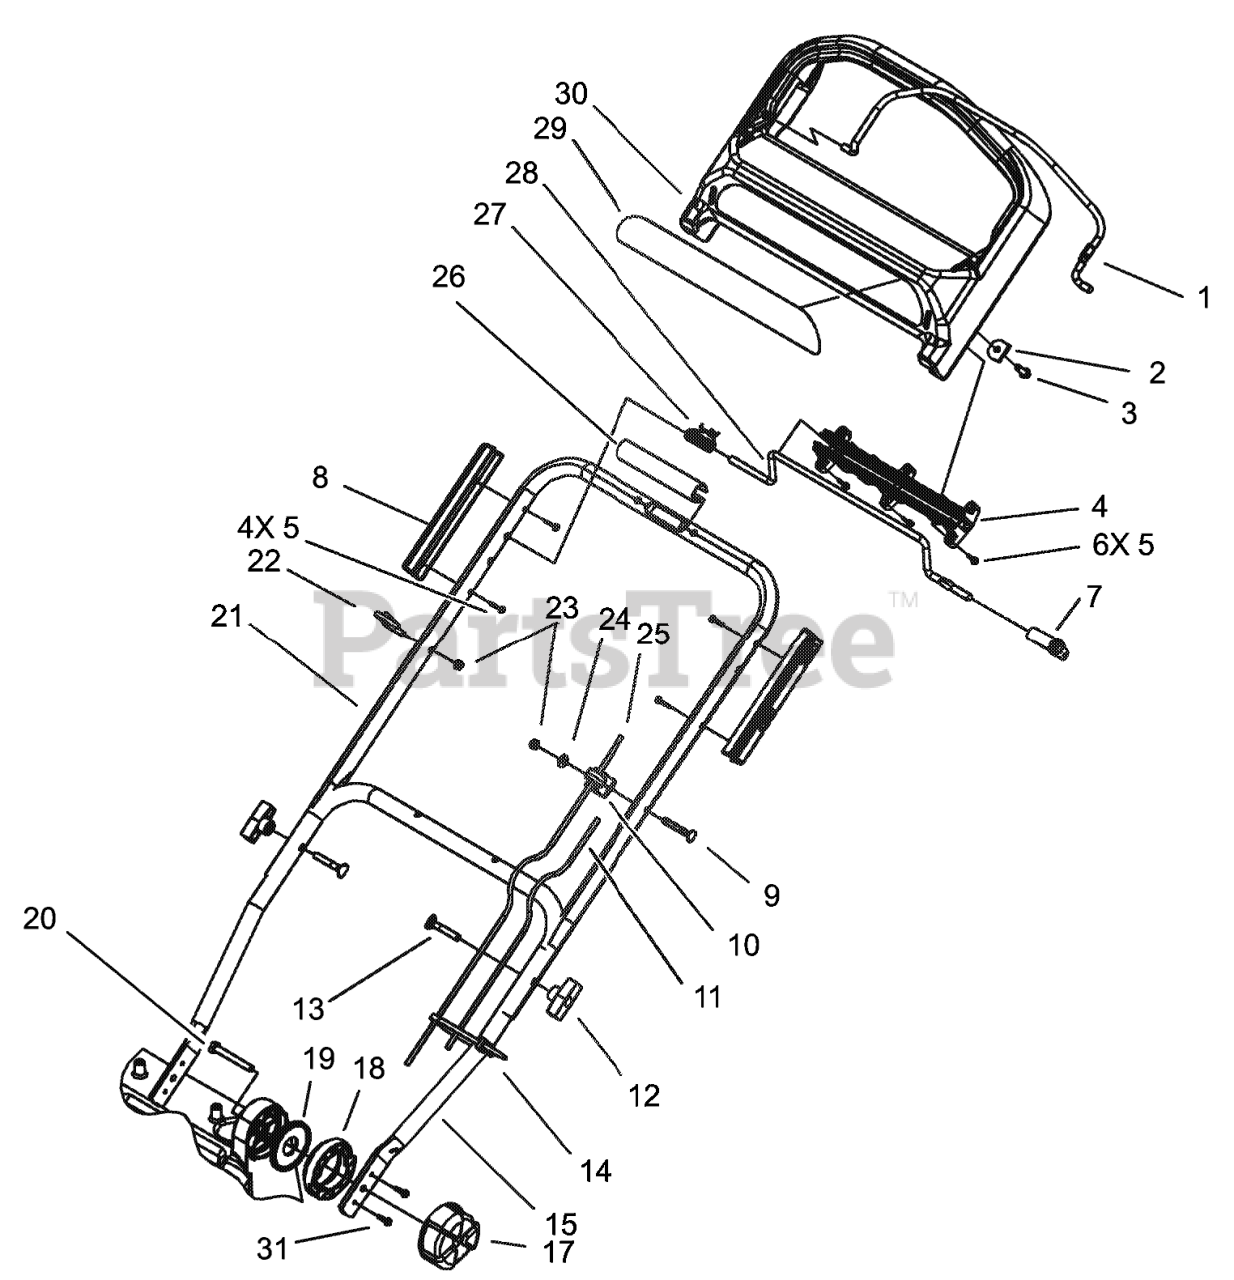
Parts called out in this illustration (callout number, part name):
1	BAIL-BRAKE
2	RETAINER-CABLE, BRAKE
3	SCREW-HWH
4	RETAINER-CONTROL ROD, TRACTION
5	SCREW-PPH
7	LEVER-TRACTION
8	GUIDE-HANDLE, CONTROL
9	SCREW
10	ANCHOR-CABLE
11	CABLE-TRACTION
12	KNOB-HANDLE
13	SCREW-HANDLE
14	TIE-CABLE
15	HANDLE-LOWER
17	KNOB-ADJUSTING, HANDLE
18	DISK-ADJUSTING, HANDLE
19	DISK-HOLDING, HANDLE
20	CAPSCREW
21	HANDLE-UPPER
22	GUIDE-ROPE
23	NUT-LOCK, NI
24	WASHER-FLAT
25	CABLE-BRAKE
26	COVER-HANDLE
27	SPRING-TORSION, RH
28	BAR-CONTROL, TRACTION
29	DECAL-AUTOMATIC
30	HANDLE-CONTROL
31	SCREW-HWH
